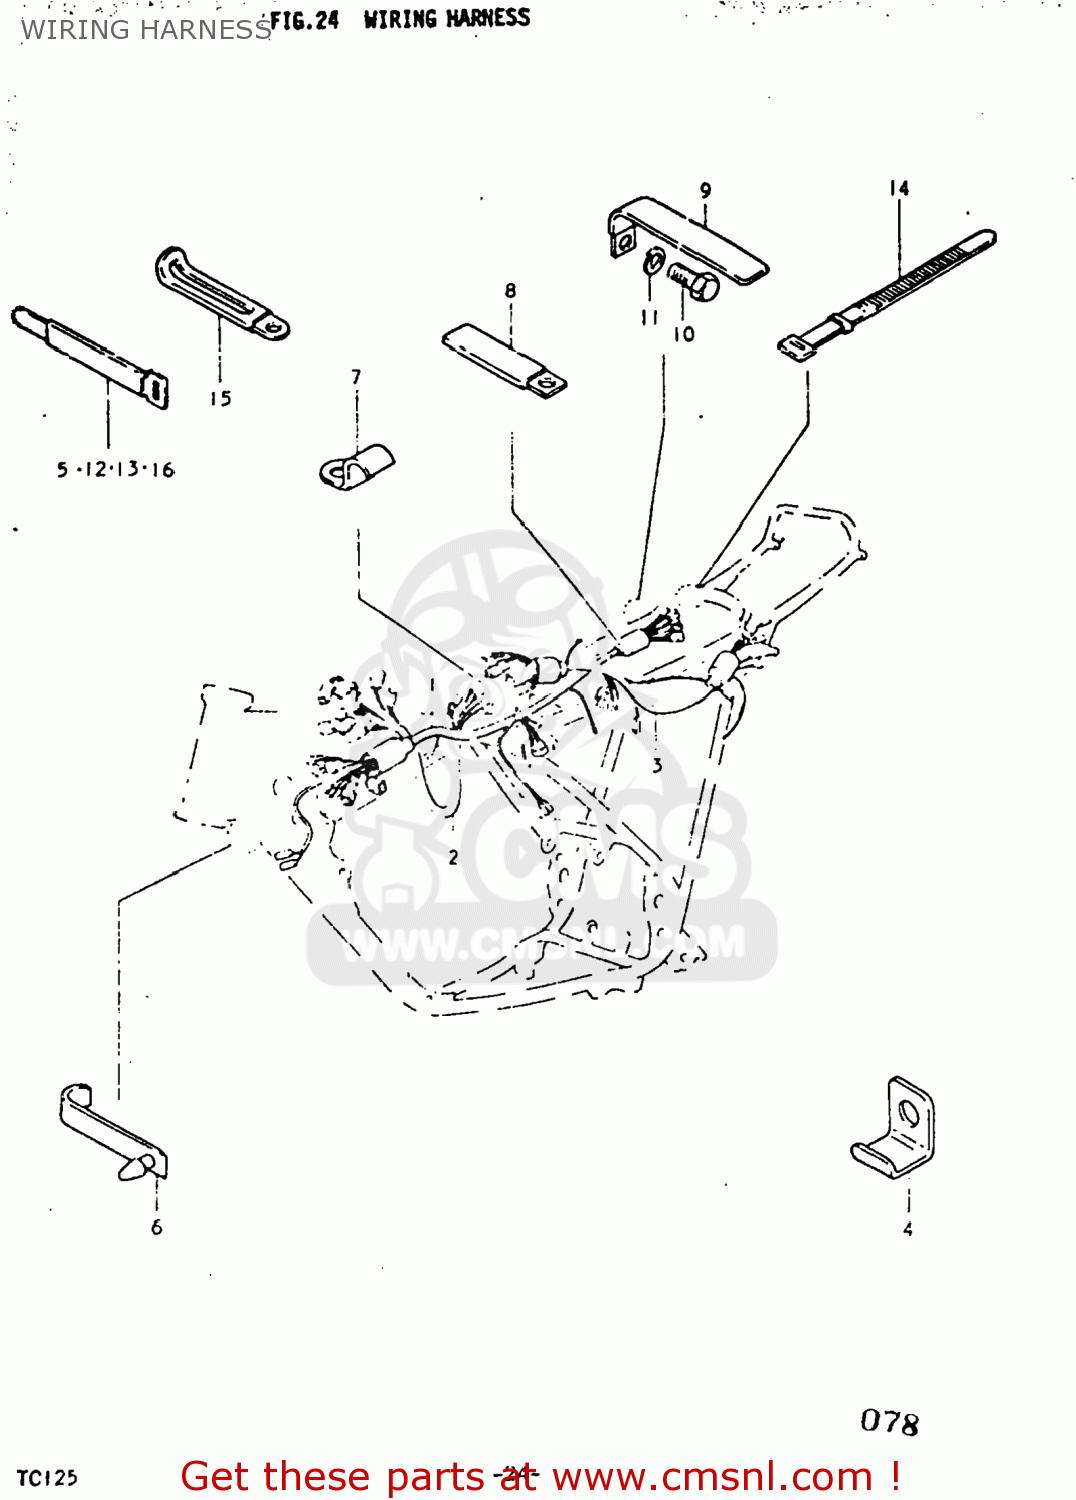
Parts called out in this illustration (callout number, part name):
1	HARNESS,WIRING
2	HARNESS,WIRING
3	HARNESS,WIRING NO.2
5	CLAMP
6	BAND
7	CLAMP
8	CLAMP
9	CLAMP
10	BOLT
11	LOCK WASHER
12	CLAMP
13	CLAMP
14	CLAMP(L:120)
15	CLAMP
16	CLAMP(L:250)
